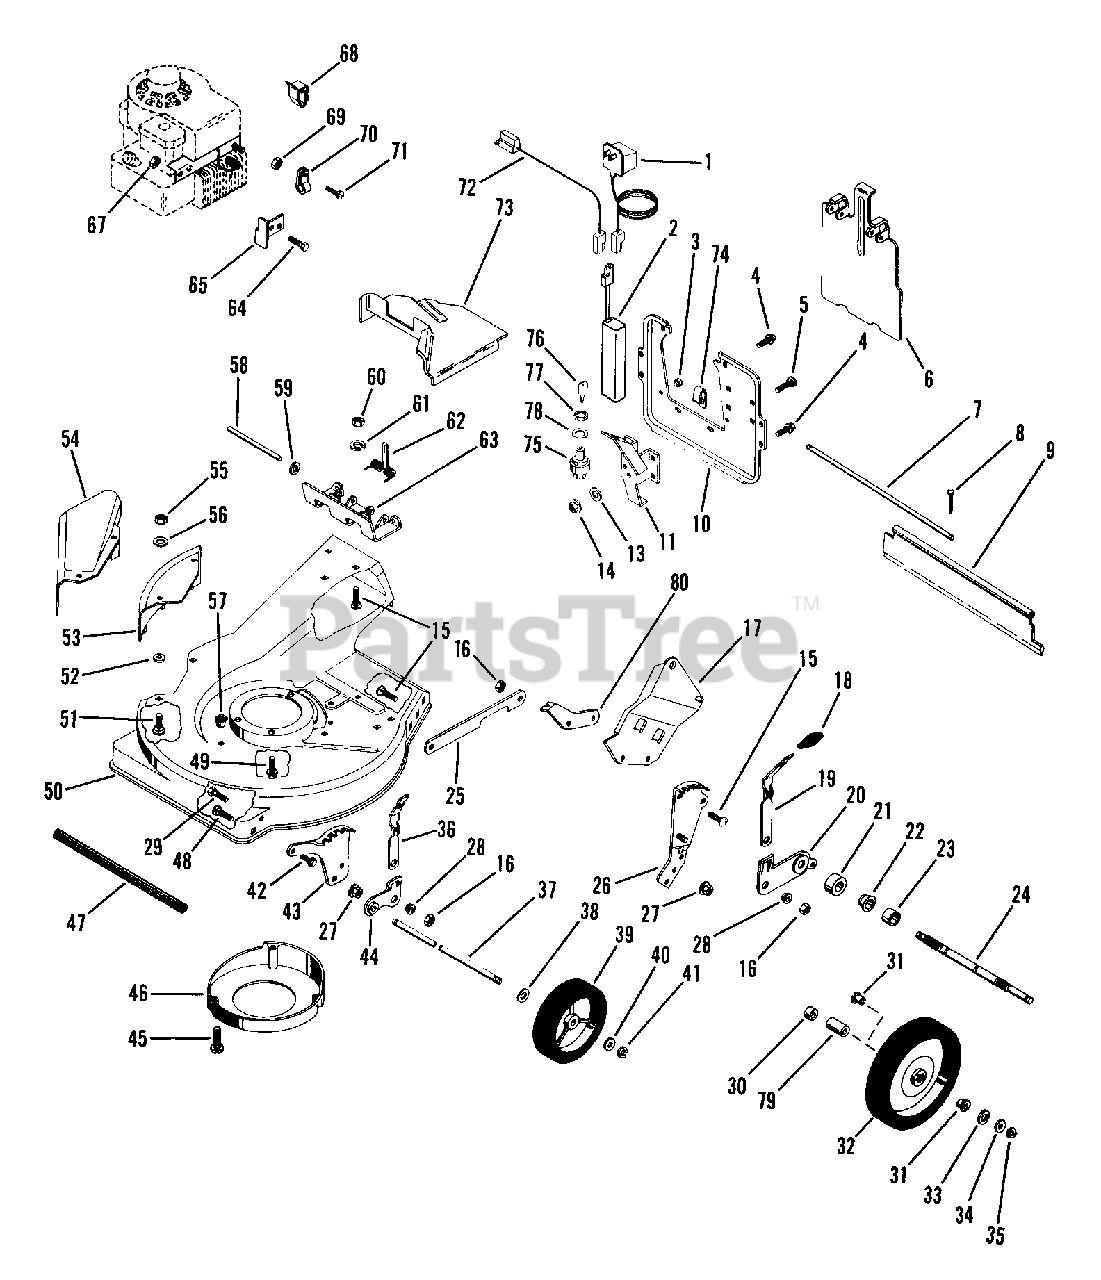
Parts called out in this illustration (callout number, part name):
1	BATTERY CHARGER
1	CHARGER - EUROPEAN
2	BATTERY
4	SCR-TAP 10-24X.375 HWH PL TR
5	BLT-RDHDSQNK .25-20X.50 SHT PL
6	DISCHARGE COVER
8	PIN-COTR .06X.50
9	REAR PROTECTIVE GUARD
10	CATCHER MOUNTING PLATE
11	SWITCH BRACKET WELDMENT
11	BATTERY BOX
13	WSHR-FL-STL .268X.562X.046 PL
14	NUT-LK-FLG .250-20 PL
15	BLT-RDHDSQNK .312-18X.62SHTPL
16	NUT-LK .312-18 GR A PL
17	LH HANDLEBAR MTG BRACKET WELDM
17	L.H. HANDLEBAR MOUNTING BRACKE
17	RH HANDLEBAR MTG BRACKET WELDM
17	R.H. HANDLE BAR MOUNTING BRACK
19	HEIGHT ADJUSTMENT LEVER
20	REAR ADJUSTMENT BRACKET L.H.
20	REAR BRACKET & BEARING ASSEMBL
20	REAR ADJUSTMENT BRACKET R.H.
21	BRG-BALL .752X1.50X.50
21	BRG-BALL .750X1.50X.44
22	SEAL .770X.708X.375
23	SPACER .78 X .74 X .39
24	REAR AXLE - PUSH MOWER
24	REAR AXLE
25	ANTIVIBRATION STRAP
26	REAR QUADRANT WELDMENT L.H.
26	REAR QUADRANT WELDMENT R.H.
27	NUT-FLG. .312-18 PL
28	BSHG-FLG .315X.500X.354X.875
29	BLT-HEX .31-18X.75 PL GR2
30	TUBE
30	SPACER
30	BSHG-SLV .625X.750X.500
31	BSHG-FLG .500X.625X.500X.750
31	BSHG-FLG .625X.750X.750X1.125
32	WHL
32	WHEEL ASSEMBLY L.H.
33	SEAL .625X.875X.125
34	WSHR-FL-STL .630X1.005X.062 PL
34	WSHR-FL-STL .505X.880X.072 PL
35	RG-RTNG-EXT .500X.042
35	RG-RTNG-EXT .438X.035
36	FRONT HEIGHT ADJUSTMENT LEVER
37	FRONT AXLE
38	WSHR-FL-STL .520X.827X.062 YZ
39	T/WHL ASSY 7X1.75 .5B
40	WSHR-FL-STL .505X.880X.072 PL
41	RG-RTNG-EXT .438X.035
42	SCR-TAP .375-16X.75 HWH PL TR
43	LEFT FRONT QUADRANT
43	RIGHT FRONT QUADRANT
44	LEFT ADJUSTOR BRACKET ASSEMBLY
44	RIGHT ADJUSTOR BRACKET ASSEMBL
45	SCR-TAP 10-16X.62 SLPH PL AB
46	CENTER BAFFLE
48	BLT-RDHDSQSHNK .31-18X.50 YZ
49	SCR-TAP .375-16X1.0 HWH PL TR
50	21 INCH MOWER PAN W/DECALS
51	BLT-RDHDSQNK .31-18X.75 SHT PL
52	NUT.75-10 PL
53	SIDE DISCHARGE COVER
54	DISCHARGE CHUTE
55	NUT-LK-NYL.312-18 PL
56	WSHR-FL-STL .38X.875X.083 PL
57	PLASTIC GROMMET
58	HINGE PIN
59	WSHR-FL-STL .265X.500X.087 PL
60	NUT-HEX .312-18
61	WSHR-LK .312X.097 PL HVY
62	SG-TORS .090X.550X2.88
63	HINGE PLATE
64	BLT-HEX .25-20X.50 PL GR2
65	LEVER GUARD
67	NUT-LK-CTR .250-20 PL
68	CLIP-HARNESS TINNERMAN
69	NUT-LK .312-18 GR A PL
70	CLIP
71	SCRW-MCH 10-32X.25 HEX PL
72	WIRING HARNESS
72	POWER CORD
73	RAIN SHIELD
75	KEY SWITCH ASSEMBLY
76	KEYS - WITH RING
77	NUT .812-20 PL
78	WSHR-LK-INT .813X.020 PL
79	SPACER .75 X .25 X .88
80	BRACKET-TRACTION CABLE MOUNTIN
